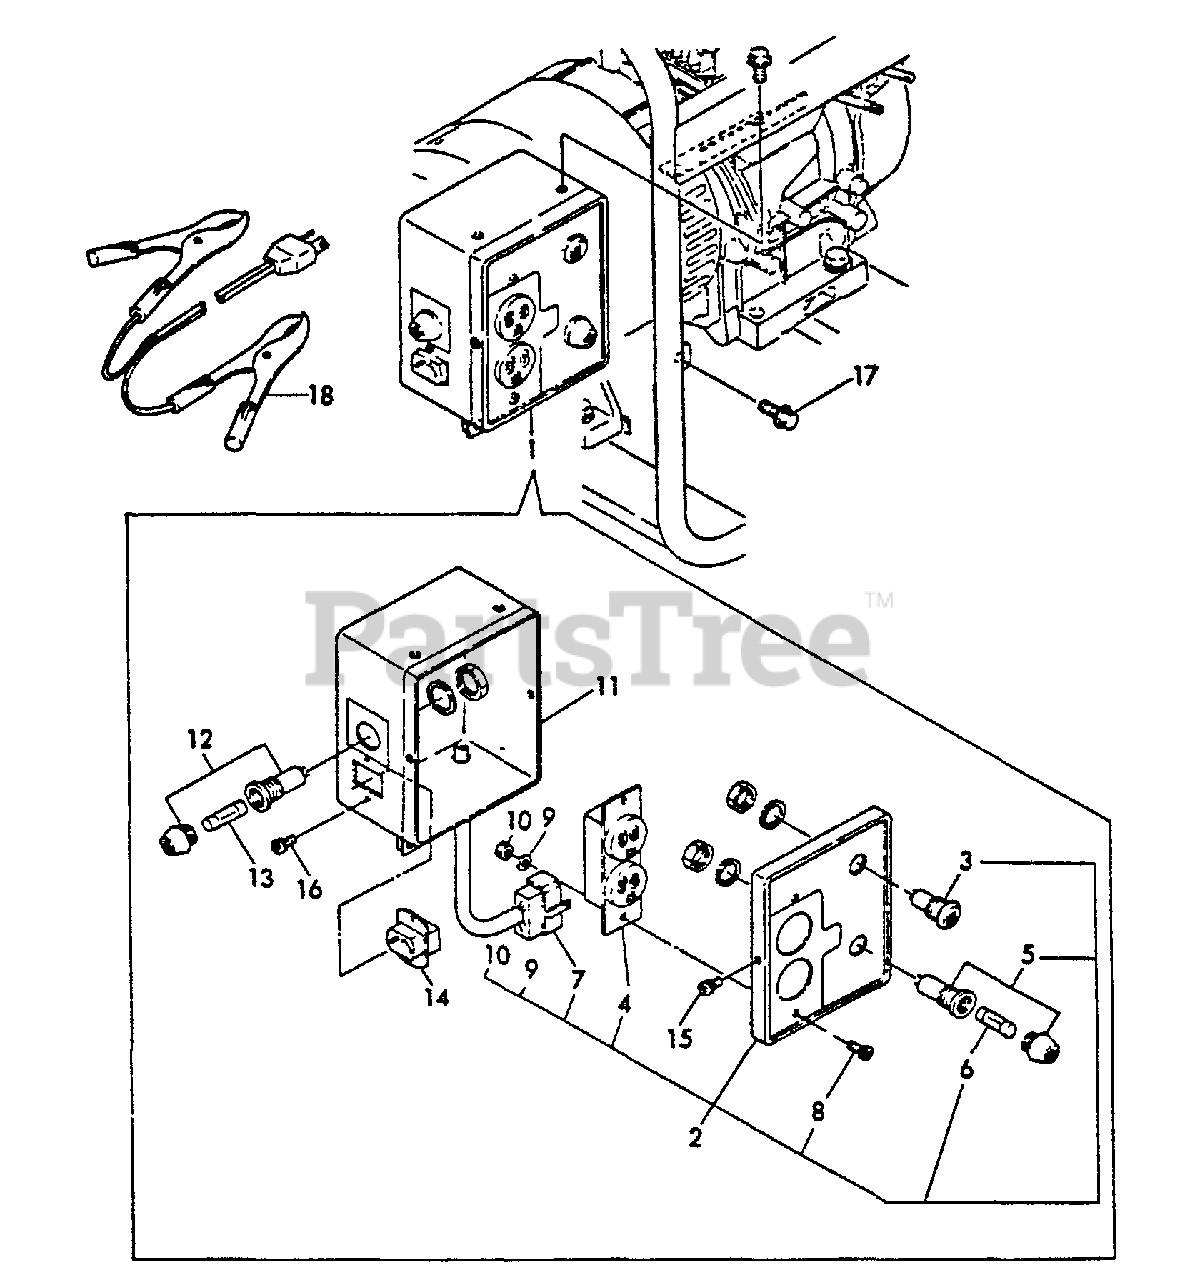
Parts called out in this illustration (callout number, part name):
1	PANEL BOX ASSY
2	PANEL ASSY
3	LAMP, PILOT - 100V
4	AC CONNECT
5	HOLDER, FUSE
6	FUSE - 12.8A
7	WIRE HARNESS
8	SCREW - 4X8
9	WASHER - 4
10	NUT - 4
11	BOX, PANEL
12	HOLDER, FUSE
13	FUSE - 15A
14	PLUG SOCKET 15A
15	SCREW - 4X8
16	SCREW - 3X10
17	BOLT - 6X8 -- PLATED
